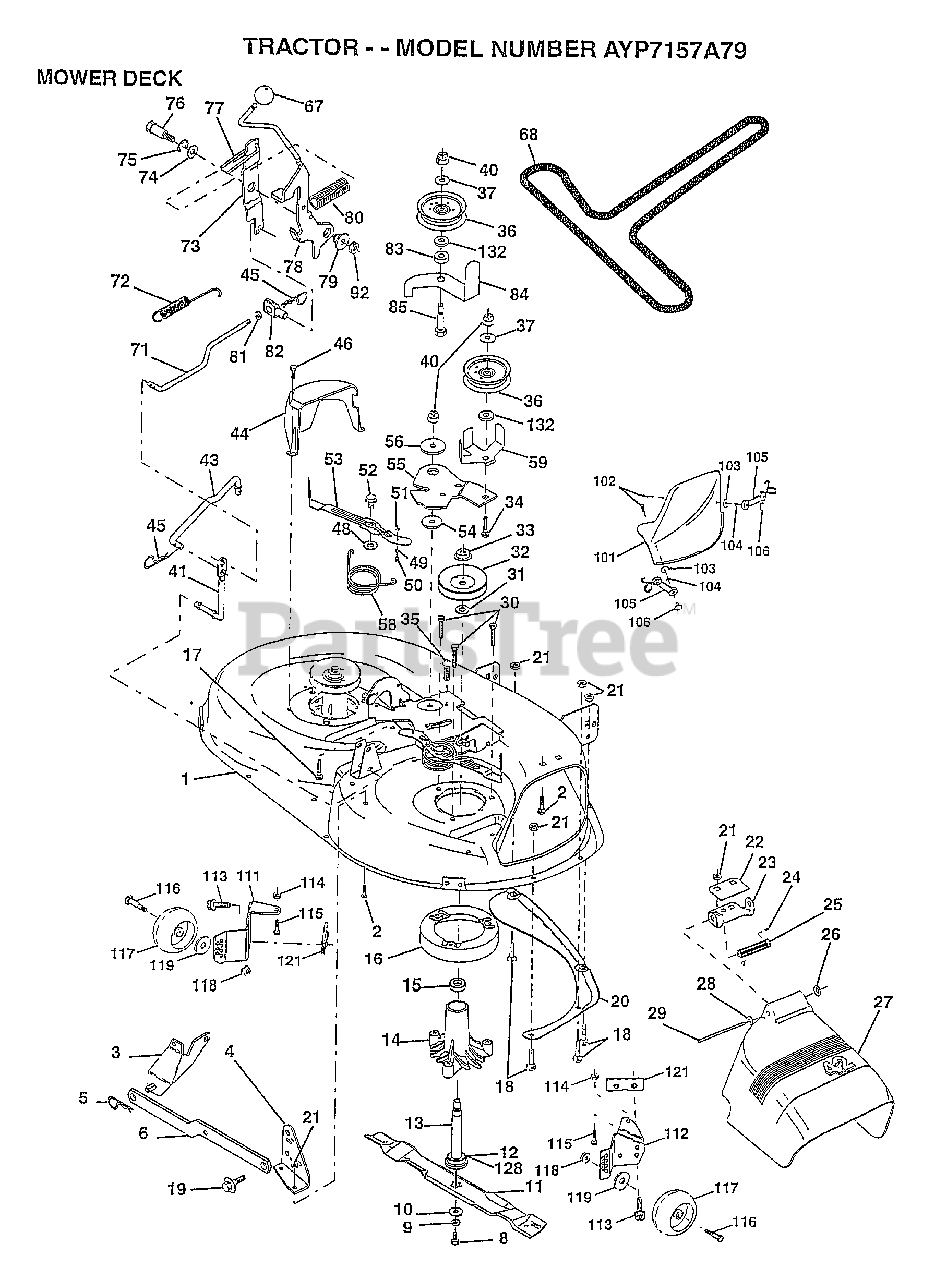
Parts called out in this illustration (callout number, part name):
1	DECK.WELD.42.
2	BOLT
3	BRKT ASM SWAY BAR
4	BRKT DECK SW BAR
8	BLADE BOLT
10	WASHER.HARD.BLADE
11	"BLADE.42"" MULCHER"
12	BEARING.BALL
14	HSG ASM MANDREL
15	BEARING
16	STRIPPER RND MWR
17	BOLT RDHD 3/8-16
18	BOLT
19	BOLT SHD 5/16-18
22	STIFFENER BRKT
23	DEFLECTOR BRKT
24	CAP-SLEEVE LT
25	SPRING TORSION
26	NUT PUSH M
27	DEFLECTOR.SHIELD
28	WASHER
29	HINGE ROD
31	WASHER
32	PULLEY.MANDREL.42
34	BOLT
35	XMAS TREE FASTNER
36	FLAT IDLER PULLEY
37	WASHER
41	PIVOT ROD
43	ROD CLUTCH W/NIBS
44	GUARD MAND LH BLK
45	RETAINER M
46	SCREW.1/4-20X5/8
48	HARD SMALL WASHER
49	ROLLER ASM-CAM
50	SHOULDER BOLT
51	LOCKNUT
52	BOLT.SHLD.5/16-18
53	BRAKE PAD ARM ASM
54	HARDENED WASHER
55	ARM-IDLER
56	SPACER RETAINER
58	SPRING TORSN BRAK
59	GUARD IDLER TUV
67	KNOB T(3/8 HOLE)
68	BELT.V.T-PATH
71	ROD CLUTCH 38/42
72	RETURN SPRING
73	CLUTCH ARM SECOND
74	WASHER
75	RING
76	SHOULDER BOLT
77	SPRING KEEPER
78	LEVER ASM-CLUTCH
79	BUSHING
80	SPRING.CLUTCH.MWR
81	NUT
82	TRUNION ADJ
83	WASHER
84	"KEEPER-BELT,FIXED"
85	BOLT RDHD 3/8-16
92	NUT
101	"COVER.MULCH.42"""
102	SCREW
103	WASHER #10
104	LOCKWASHER
106	WELDNUT
111	BRACKET.GWHL.LH.
112	BRACKET.GWHL.RH.
113	SCREW
116	BOLT.SHOULDER
117	WHEEL GAGE DONUT
118	LOCKNUT
119	WASHER
121	BRACKET.EXTRD.GWL
128	WASHER.FELT.
132	WASHER GT
